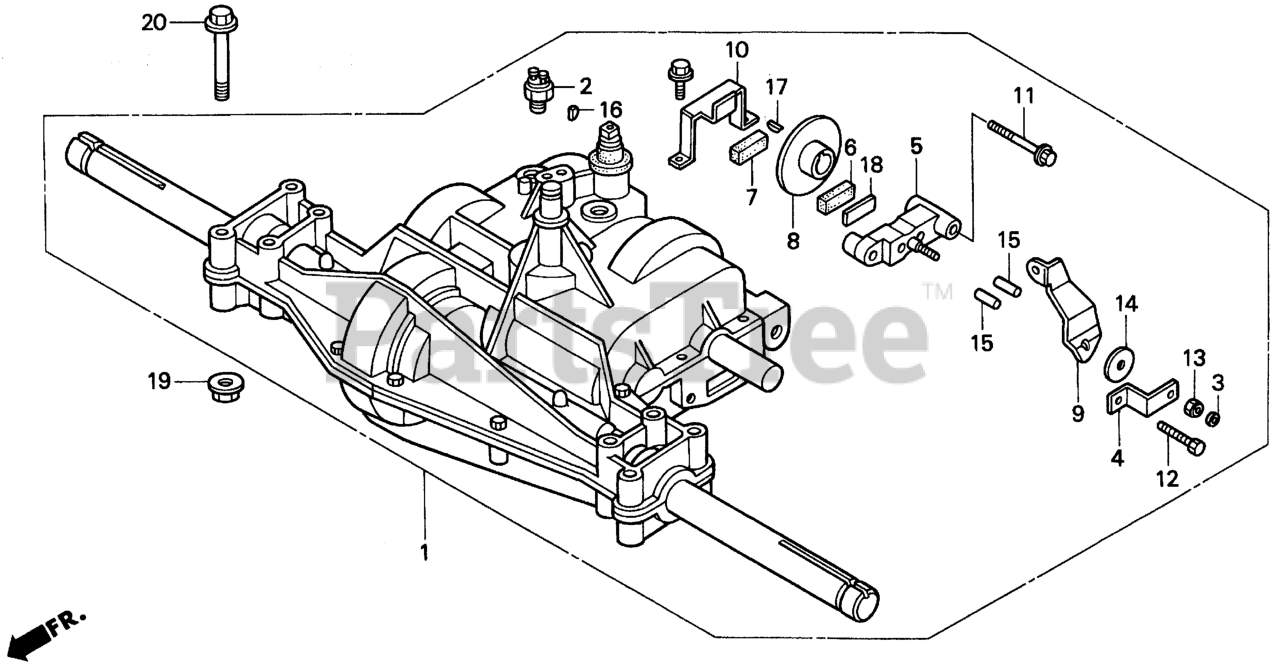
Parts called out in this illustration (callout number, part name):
1	TRANSMISSION ASSY.
2	SWITCH ASSY., NEUTRAL
3	INDICATOR, BRAKE
4	BRACKET, ANTI-ROTATION
5	HOLDER, BRAKE PAD
6	PUCK A, FRICTION
7	PUCK B, FRICTION
8	DISK, BRAKE
9	ARM, RR. BRAKE
10	STOPPER, BRAKE ARM
11	SCREW, TAPPING (5/16)
11	SCREW, TAPPING (5/16-18X2.35)
12	SCREW, TAPPING (5/16X1.44)
12	SCREW, TAPPING (5/16-18X2.35)
13	NUT, LOCK (5/16-24)
14	WASHER, PLAIN (0.32)
15	PIN, DOWEL
16	KEY, WOODRUFF (#9)
17	KEY, WOODRUFF
19	NUT, FLANGE (8MM)
20	BOLT, FLANGE (8X65)
